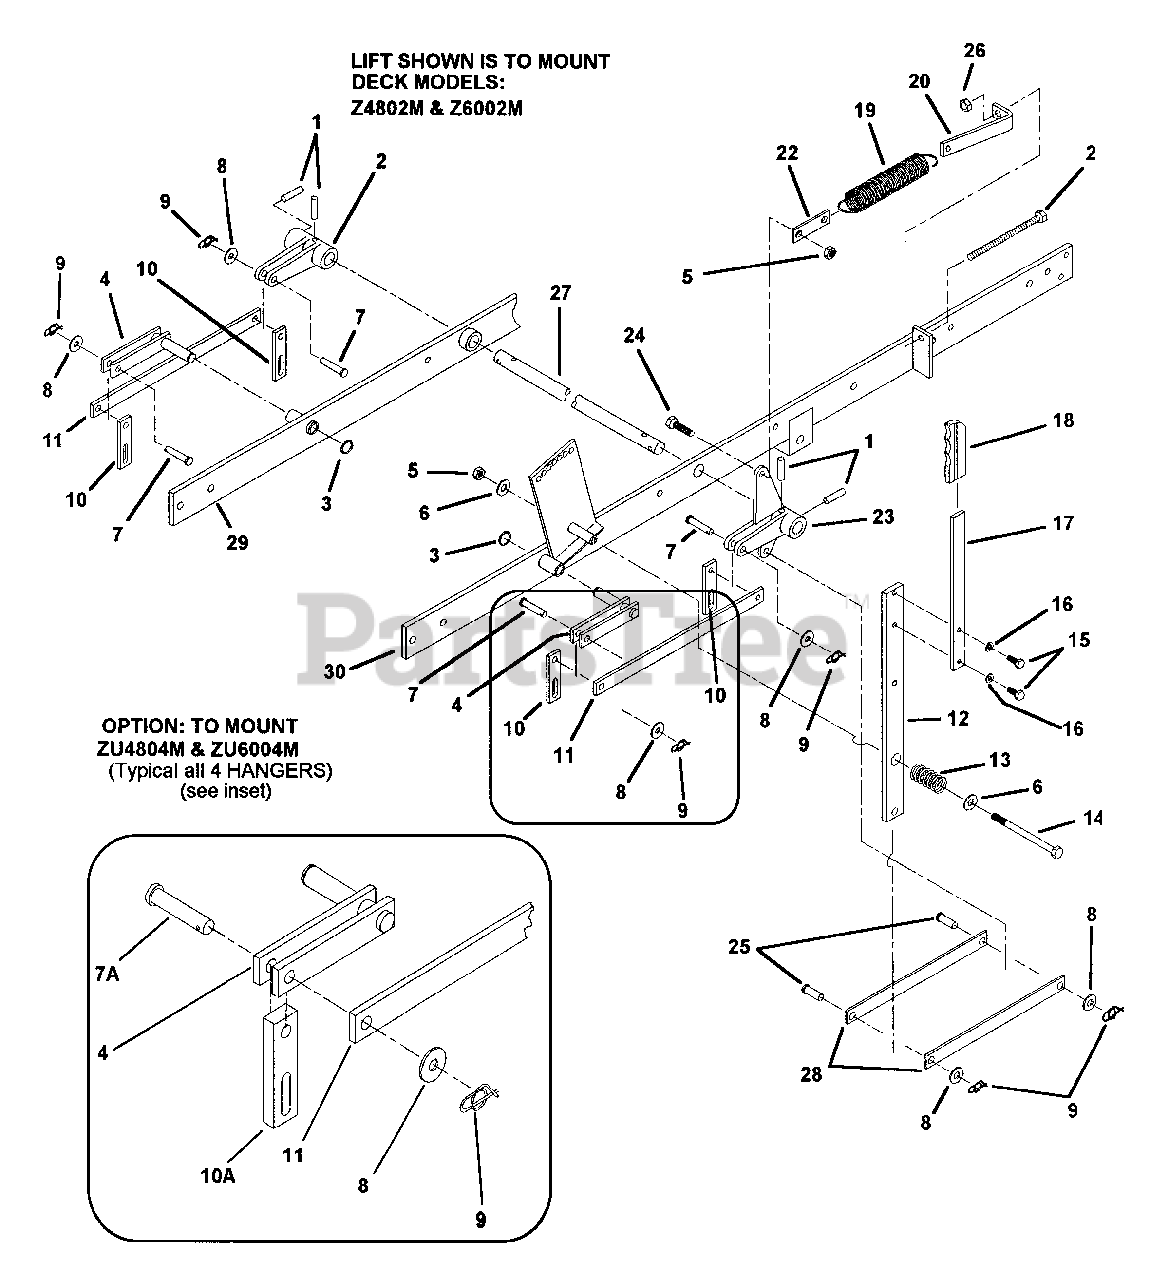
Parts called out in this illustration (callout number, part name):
1	ROLL PIN, 5/16 X 1-1/4 HBK
2	LIFT SLEEVE, R.H.
3	RING, 5/8" External Retaining
4	DECK HANGER WELDMENT
5	NUT, 3/8-16, NYLOC
6	WASHER, FLAT STD. 3/8"
7	CLEVIS PIN, 5/16 X 1-1/2" LONG
7A	CLEVIS PIN, 5/16 X 1-3/4" LONG
8	WASHER, FLAT STD. 5/16"
9	COTTER RUE RING, 5/16-3/8
10	DECK HANGER BAR
10A	DECK HANGER BAR: HEAVY DUTY
11	BAR, CONNECTING
12	LOWER HANDLE WELDMENT
13	SPRING, COMPRESSION, .975 O.D.
14	BOLT, 3/8-16 X 3" GR. 5
15	BOLT, 1/4-20 X 3/4" GR. 5
16	LOCK WASHER, 1/4" SPLIT SPRING
17	TOP DECK HANDLE
18	GRIP, HANDLE
19	SPRING, EXT., 1.65 O.D. X 9"
20	SPRING TIGHTENER
22	SPRING EXTENSION
23	LIFT SLEEVE, L.H.
24	BOLT, 3/8-16 X 1-1/4" GR. 5
25	CLEVIS PIN, 3/8 X 1"
26	NUT, HEX. 3/8-16 UNC-2B
27	LIFT BAR
28	HANDLE LINK
29	FRAME SIDE WELDMENT, R.H.
30	FRAME SIDE WELDMENT, L.H.
